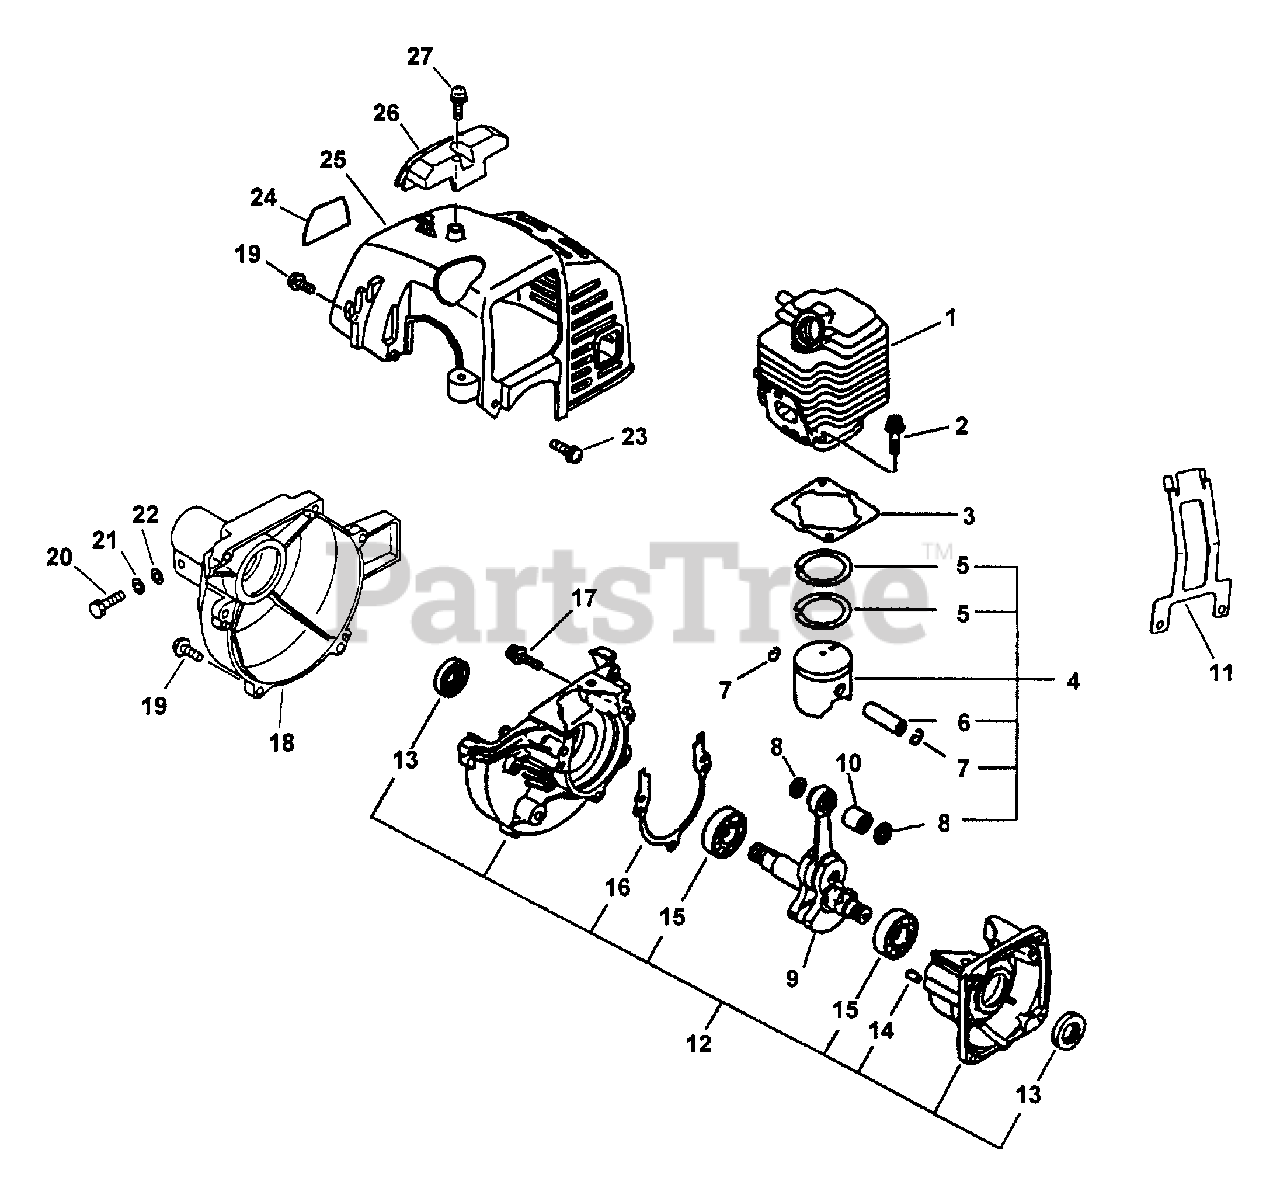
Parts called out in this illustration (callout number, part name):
1	CYLINDER
2	SCREW - 5X22
3	GASKET, CYLINDER
4	PISTON KIT
5	RING, PISTON
6	PIN, PISTON
7	RING, RETAINING
8	SPACER, PISTON
9	CRANKSHAFT ASSY
10	BEARING, NEEDLE
11	GUARD, ENGINE
12	CRANKCASE KIT
13	SEAL, OIL
14	PIN - LOCATING
15	BEARING, BALL - 6201
16	GASKET, CRANKCASE
17	SCREW - 5X28
18	CASE, FAN - ORANGE
19	SCREW - 4X16
20	BOLT - 5X25
21	LOCKWASHER - 5
22	WASHER - 5
23	SCREW - 4X12
24	LABEL - MODEL
25	COVER, ENGINE - ORANGE
26	GUARD, TOP - BLACK
27	SCREW - 5X16 -- TAPPING
